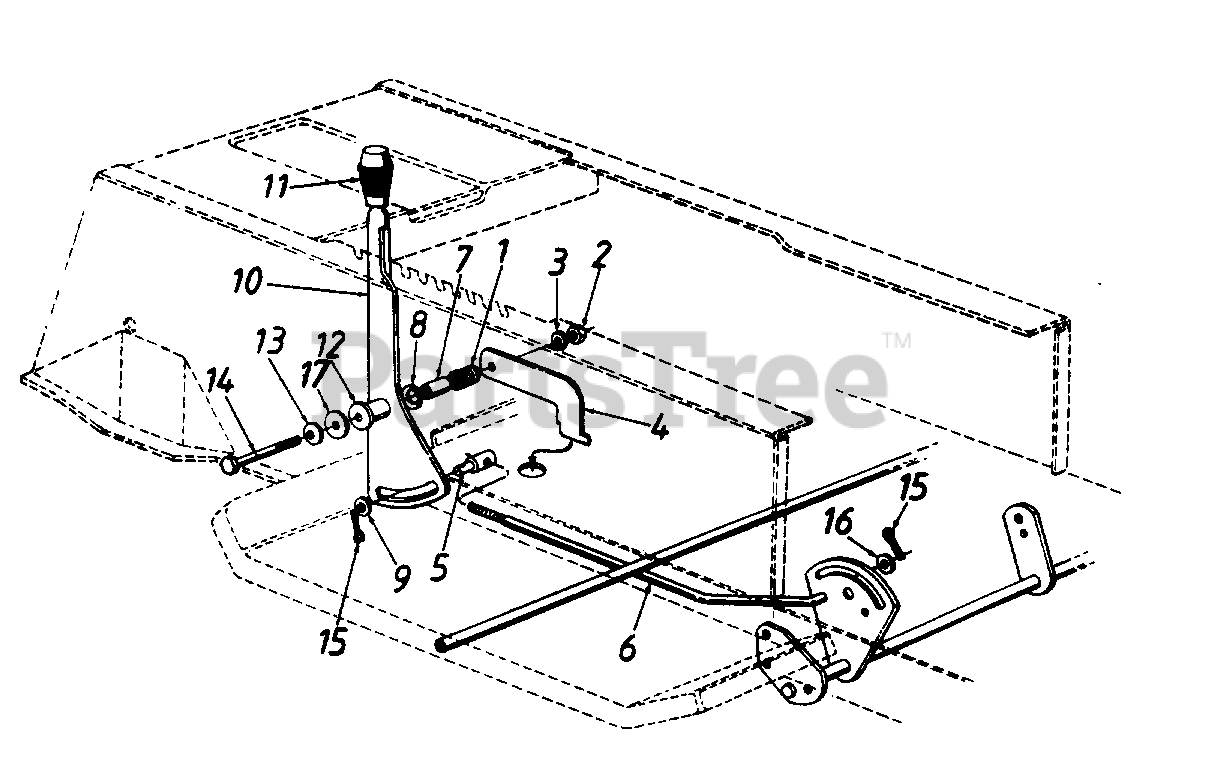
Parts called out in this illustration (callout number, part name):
1	Compression Spring
2	Hex Nut 5/16-18 Thd.
3	L-Wash. 5/16" I.D.
4	Shift Lever Support
5	Ferrule 3/8-24 Thd.
6	Speed Control Rod
7	Spacer 1.56" Lg.
8	Bell-Wash. .505" I.D. x 1"
9	Fl-Wash. .385" I.D. x .87"
10	Speed Selector Lever
11	Shift Knob
12	Spacer 1.46" Lg.
13	Bell-Wash. .345" I.D. x .88"
14	Hex Bolt 5/16-18 x 3.25" Lg.
15	Cotter Pin 3/32" Dia. x 1"
16	Fl-Wash. .469" I.D. x .88"
17	Fl-Wash. .34" I.D. x 2.25"
